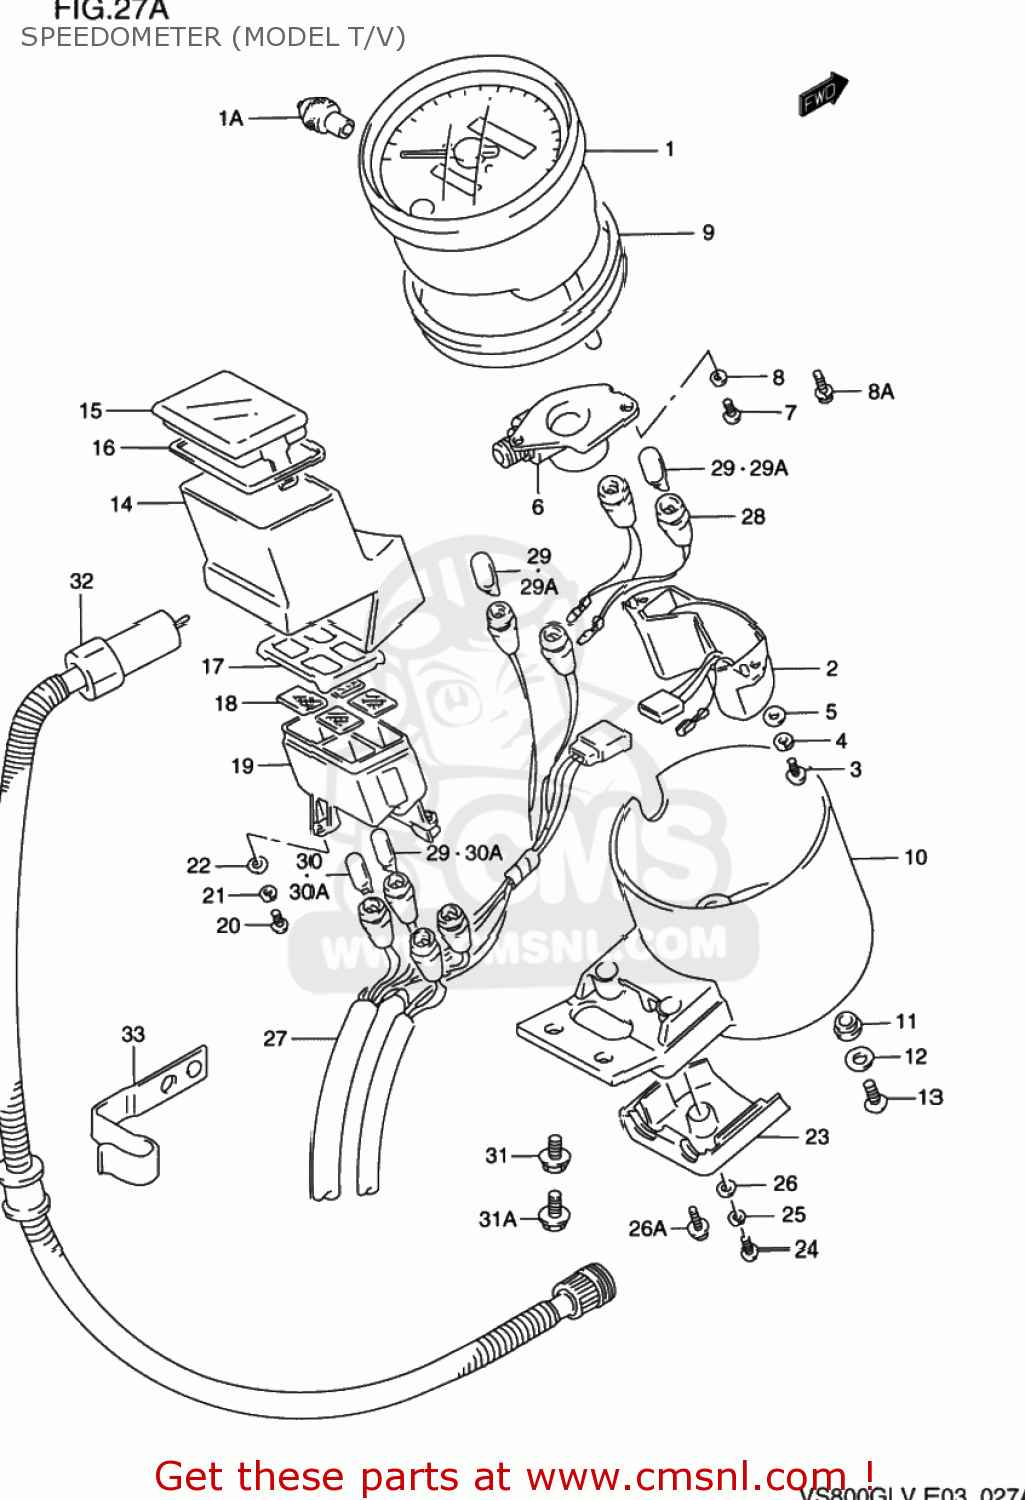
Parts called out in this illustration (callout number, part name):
1	SPEEDOMETER (MILE/KILO)
1A	KNOB,TRIP
2	UNIT,WATER TEMP
3	SCREW
4	WASHER,LOCK
5	WASHER
6	BOX,GEAR
7	SCREW
8	WASHER,LOCK
8A	SCREW
9	CUSHION
10	COVER,METER
11	CUSHION,METER
12	WASHER
13	SCREW
14	BOX,PILOT
15	LENS,PILOT BOX
16	CUSHION
17	PLATE,PILOT LENS
18	LENS SET
19	CASE,PILOT LAMP
20	SCREW
21	WASHER,LOCK
22	WASHER
23	COVER,PILOT BOX
24	SCREW
25	WASHER,LOCK
26	WASHER
26A	SCREW
27	SOCKET,METER NO.1
28	SOCKET
29	BULB(12V3W,T6.5)
29A	BULB(12V3W,T6.5)
30	BULB(12V1.7W,T6.5)
30A	BULB(12V1.7W,T6.5)
31	BOLT
31A	SCREW
32	CABLE ASSY,SPEEDOMETER
33	GUIDE,SPEEDOMETER CABLE
